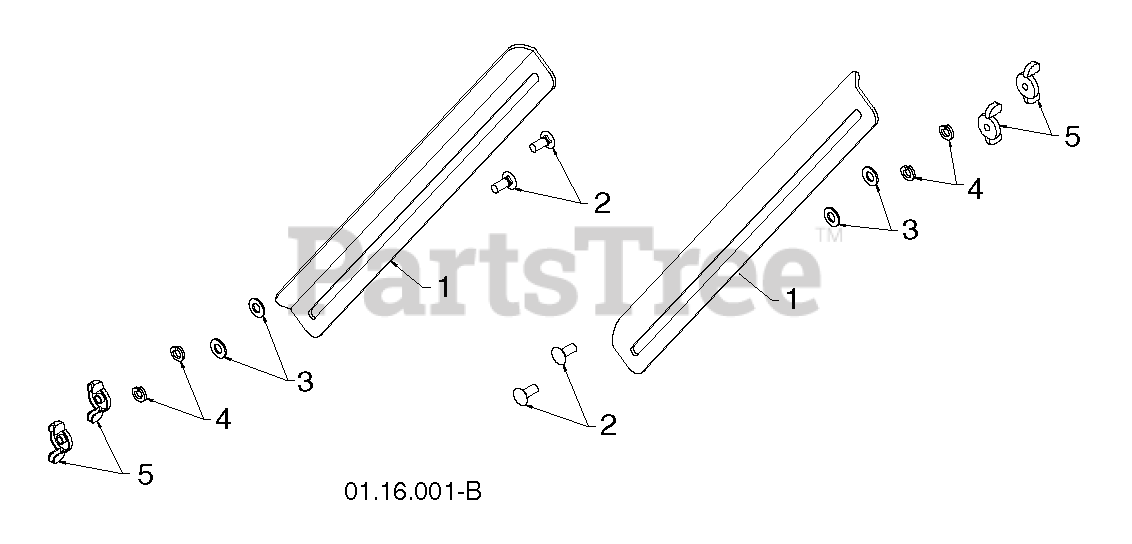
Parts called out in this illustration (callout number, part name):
1	DRIFT CUTTER BAR
2	BOLT
3	WASHER, NYLON FRICTION
4	LOCKWASHER
5	NUT WING PM
